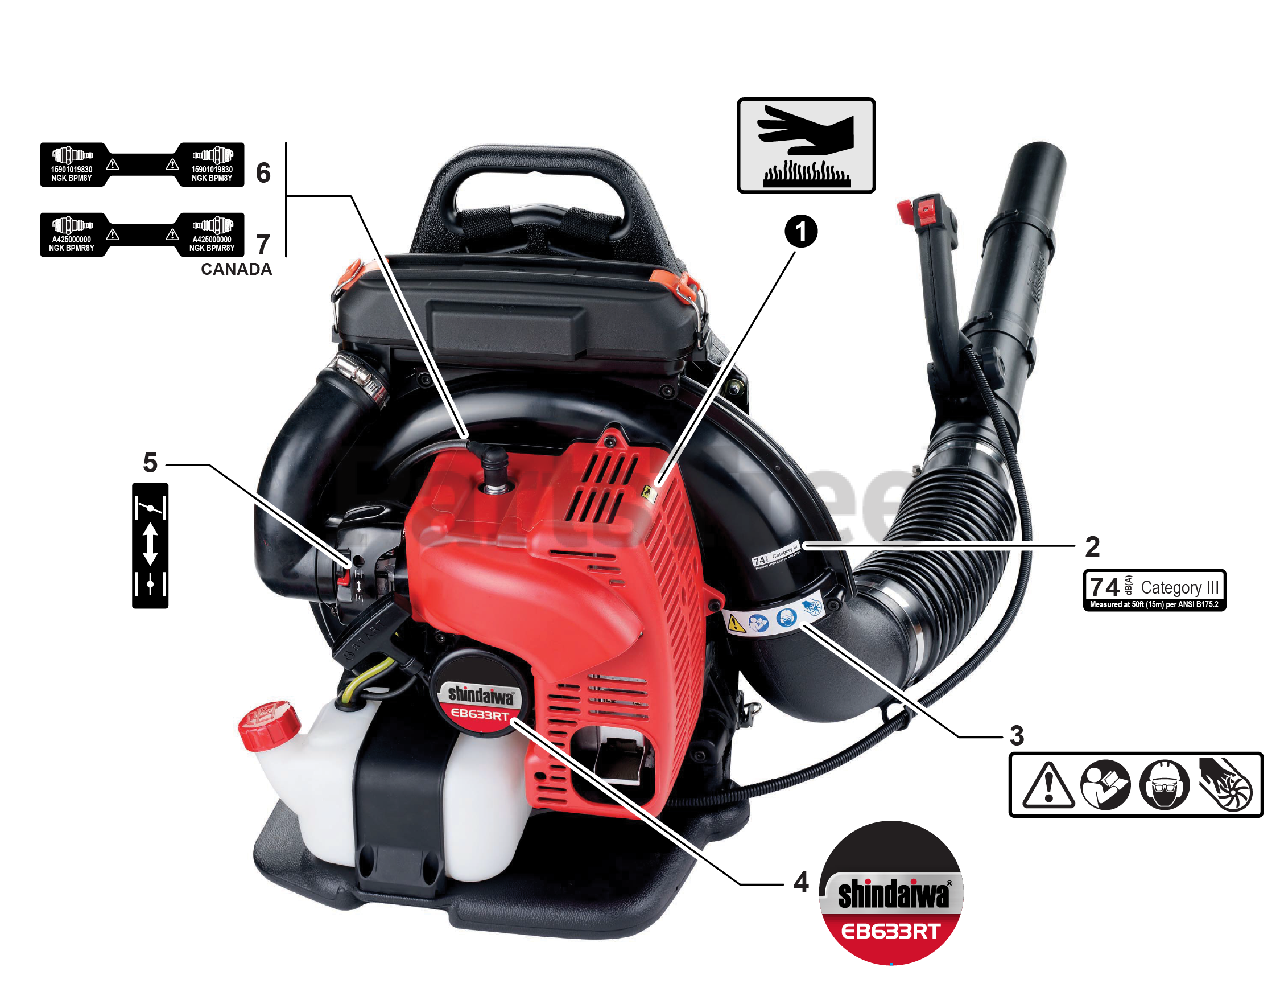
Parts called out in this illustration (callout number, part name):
1	LABEL, CAUTION - HOT
2	LABEL, NOISE
3	LABEL, CAUTION - ISO
4	LABEL, MODEL - EB633RT
5	LABEL, CHOKE
6	LABEL, SPARK PLUG - BPM8Y
7	LABEL, SPARK PLUG - BPMR8Y
